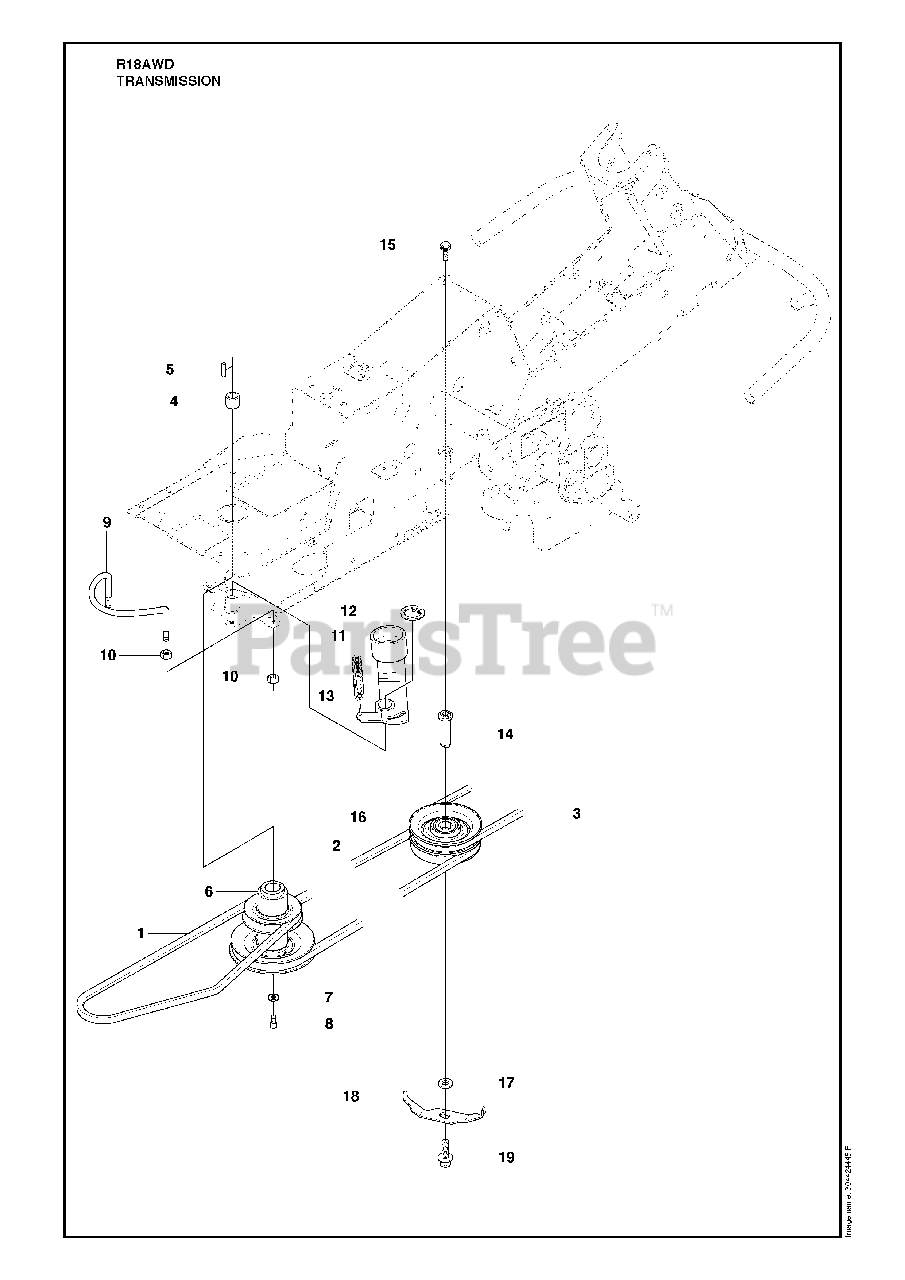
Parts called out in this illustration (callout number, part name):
1	BELT
2	BELT
3	BELT
9	Belt Guide
10	NUT
12	RETAINING RING SGA 25
14	SHAFT
18	BELT GUIDE
19	BOLT
